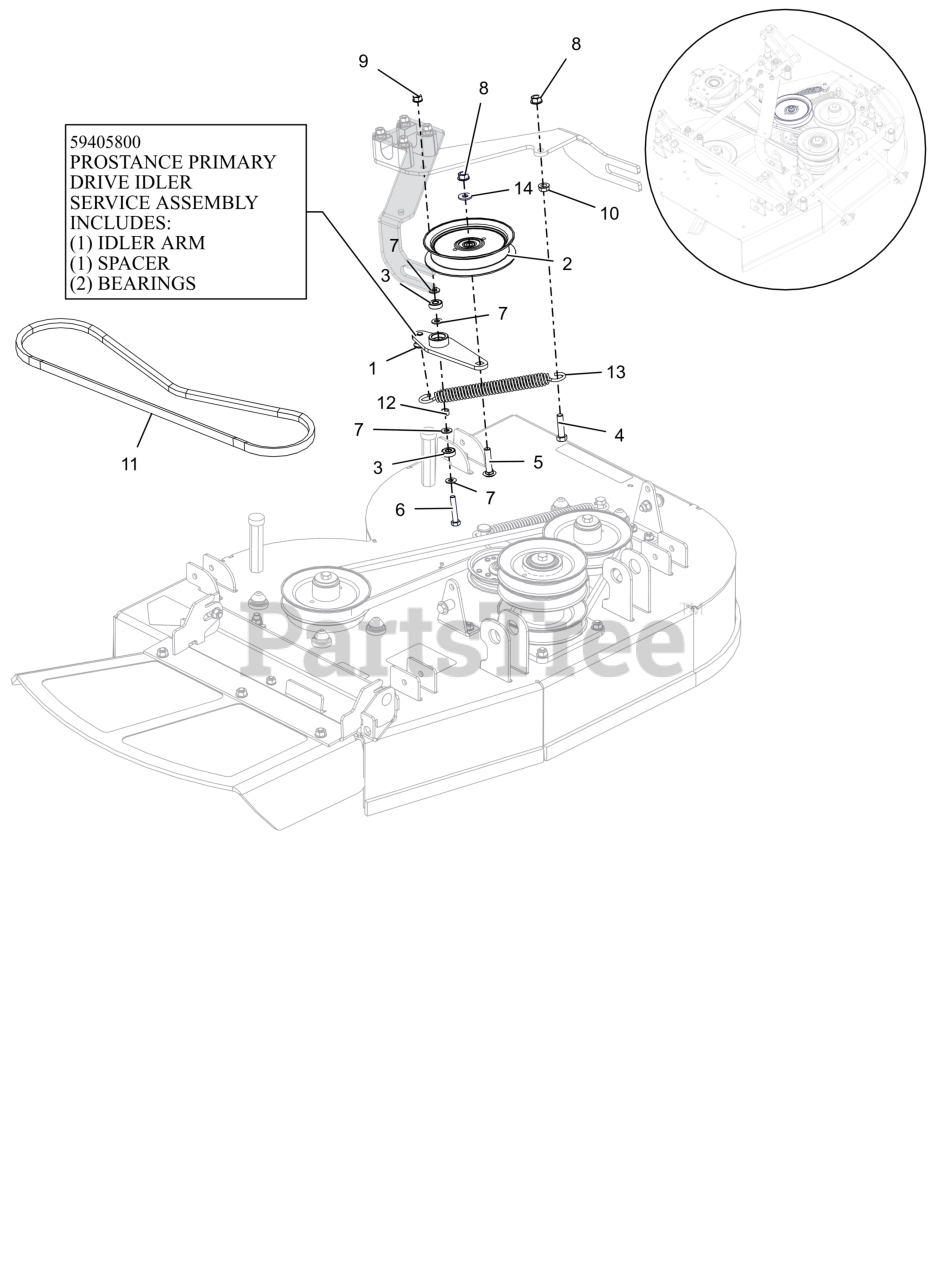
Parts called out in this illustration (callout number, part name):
1	WLDMT, IDLER ARM
2	IDLER, FLAT 5.00"
3	BRG-BALL .315X.866X.276(608)
4	BLT, HEX .38-16X1.50 G5 ZCC
5	BTL,RHSSN .375-16 X 1.75 G5 ZCC
6	BLT, HEX .31-18X1.75 G5 ZCC
7	WSHR, HRDN 0.344X0.688X0.065
8	NUT-LK-CTR-FLG .375-16 GF ZCC
9	NUT,LK-CTR-FLG .31-18 GF ZCC
10	NUT, SPNLK-FLG .38-16 G5 ZCC
11	V-BELT, 5L RAW EDGE EPDM
12	SPCR- SLV .344 X .500 X .283
13	SPRING, EXTENSION
14	WSHR,FLT .375X.875X.083 ZCC
